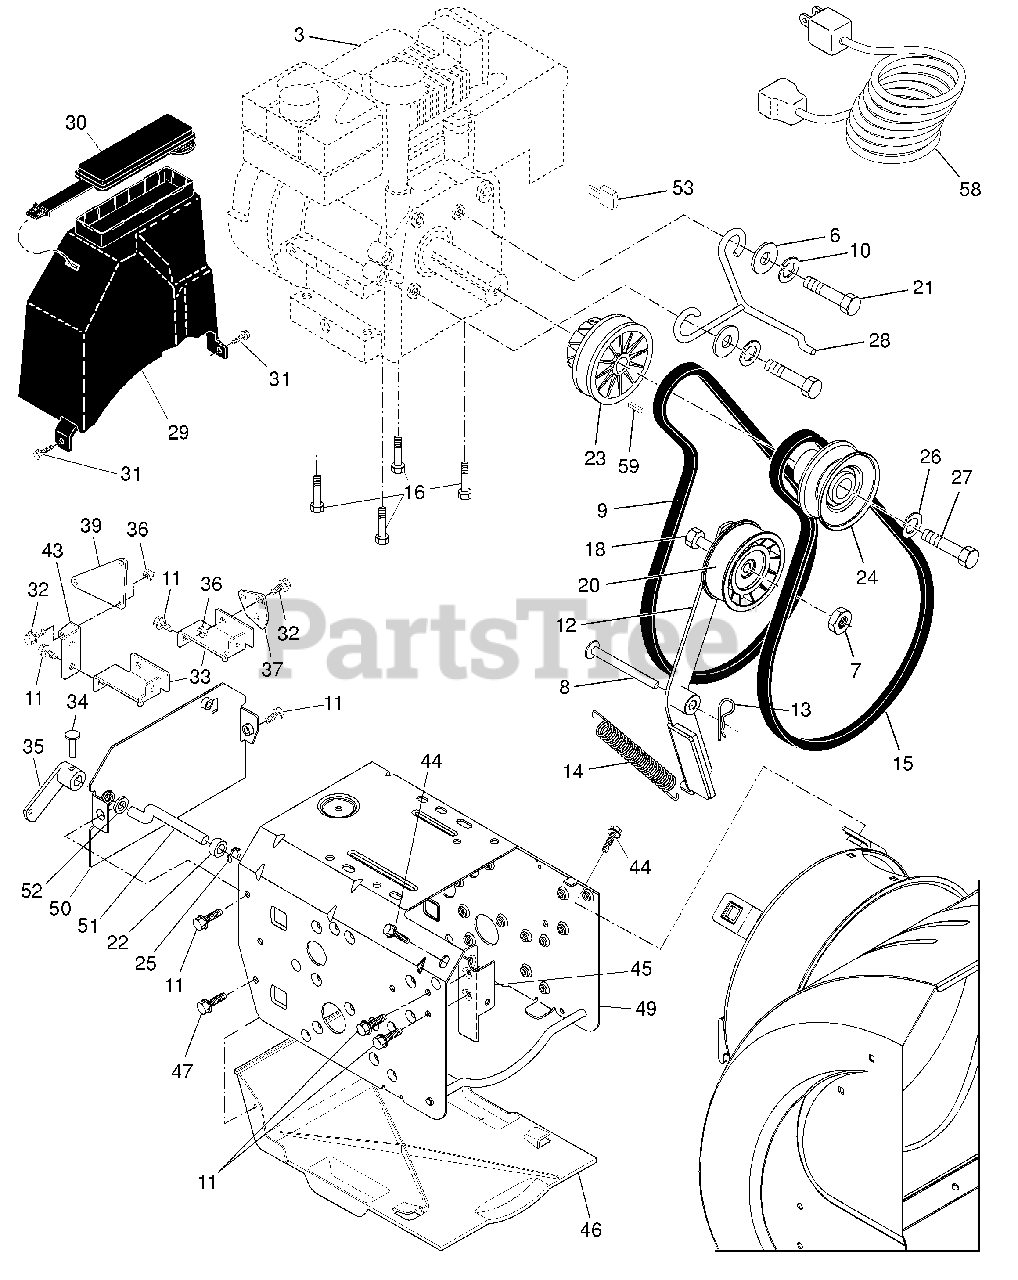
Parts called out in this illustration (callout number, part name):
6	Washer, Flat
7	Nut, Jam, Lock 5/16-18
8	Pin, Idler Pivot
9	Belt, Traction Variator
10	Washer, Lock 5/16
11	Screw, Hex Head 5/16-18 x 1/2
12	Idler Arm / Brake Pad Assembly
13	Retainer, Hairpin
14	Spring, Brake
15	V-Belt, Impeller Drive
16	Screw, Hex Head 3/8-16 x 1-1/4
18	Screw, Hex Head 5/16-18 x 1-1/2
20	Pulley, Idler
21	Screw, Hex Head 5/16-18 x 1
22	Roller, Actuator
23	Pulley, Engine, Variator
24	Pulley, Engine, Impeller Drive
25	Ring, Crescent
26	Washer, Lock 3/8
27	Screw, Hex Head 3/8-24 x 1-3/8
28	Guide, Belt
29	Belt Cover Assembly
30	Cover, Toolbox
31	Screw, Hex Head 1/4-20 x 1/2
32	Bolt, Shoulder
33	Bracket, Cable, Rear
34	Clevis Pin
35	Arm, Auger Control
37	Plate, Clutch
39	Plate, Speed, Pivot
43	Bracket, Speed, Pivot
44	Screw, Hex Head
45	Bracket, Pivot, Idler
46	Pan, Frame Bottom
47	Screw, Hex Head 5/16-18 x 3/4
49	Frame Assembly
50	Plate, Frame End
51	Shaft, Auger Control
52	Washer, Hardened
53	Key, Safety
58	Power Cord
59	Key, Square, Variator Pulley
